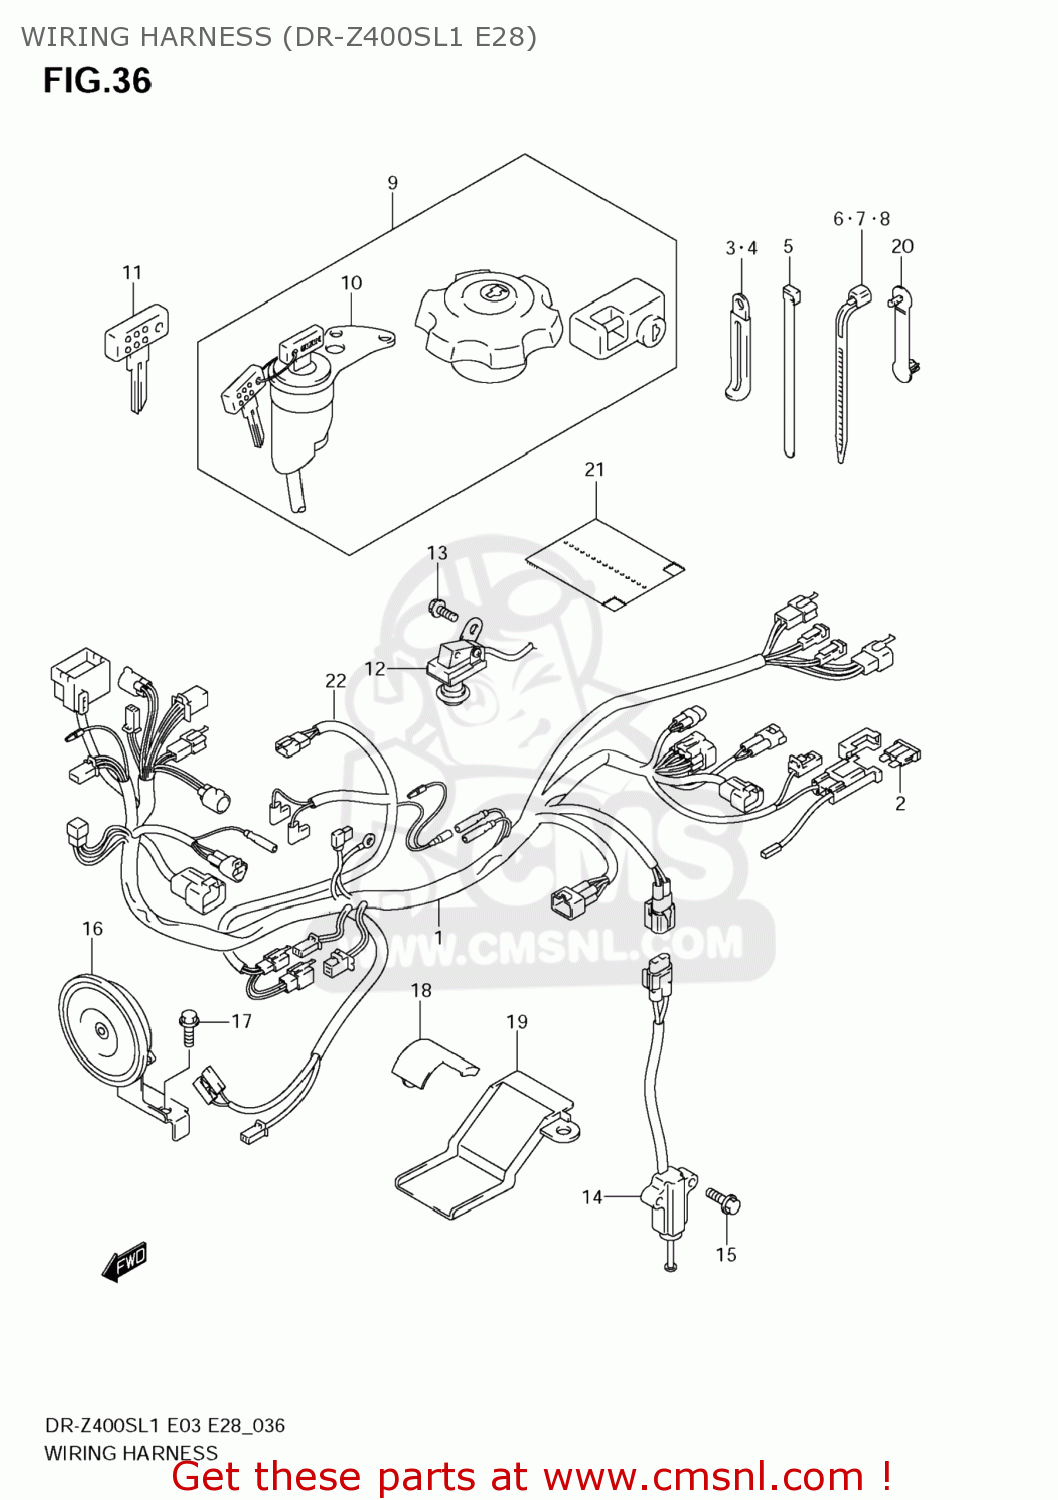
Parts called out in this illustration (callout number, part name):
1	HARNESS,WIRING
2	FUSE(20A)
3	CLAMP(L:45)
4	CLAMP(L:80)
5	CLAMP(L:145)
6	CLAMP(L:125)
7	CLAMP(L:165)
8	CLAMP(L:235)
9	LOCK SET
10	SWITCH ASSY,IGNITION
11	KEY,BLANK(TYPE:C)
12	SWITCH ASSY
13	SCREW
14	SWITCH ASSY,SIDE STAND
15	BOLT
16	HORN ASSY
17	BOLT
18	PROTECTOR,WIRING HARNESS
19	PROTECTOR,WIRING HARNESS
20	CLAMP(L:63)
21	COVER,WIRING HARNESS
22	WIRE,CARB HEATER
